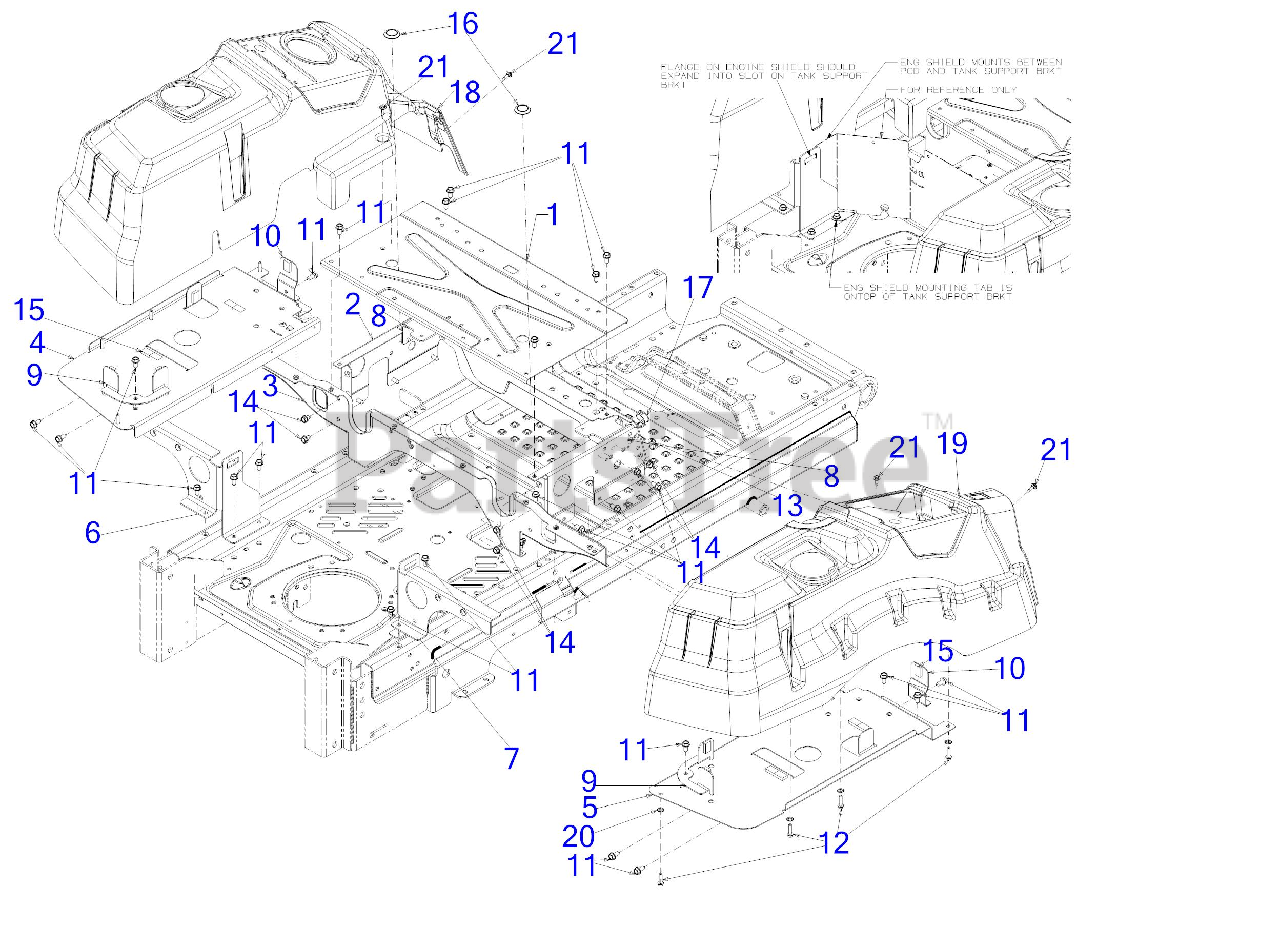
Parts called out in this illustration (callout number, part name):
8	SEAT BOX BRACKET
11	SCREW 5/16-18 x .750
12	SCREW 5/16-14 x 1
13	SCREW 5/16-18 x .750
14	SCREW 5/16-18 x .500
15	FOAM TAPE .625 WIDE x .25 THK BULK
17	PLASTIC PLUG
18	CONSOLE (LH) Z-STYLE
19	CONSOLE (RH) Z-STYLE
21	SHOULDER SCREW M6-1 .368 X.115
